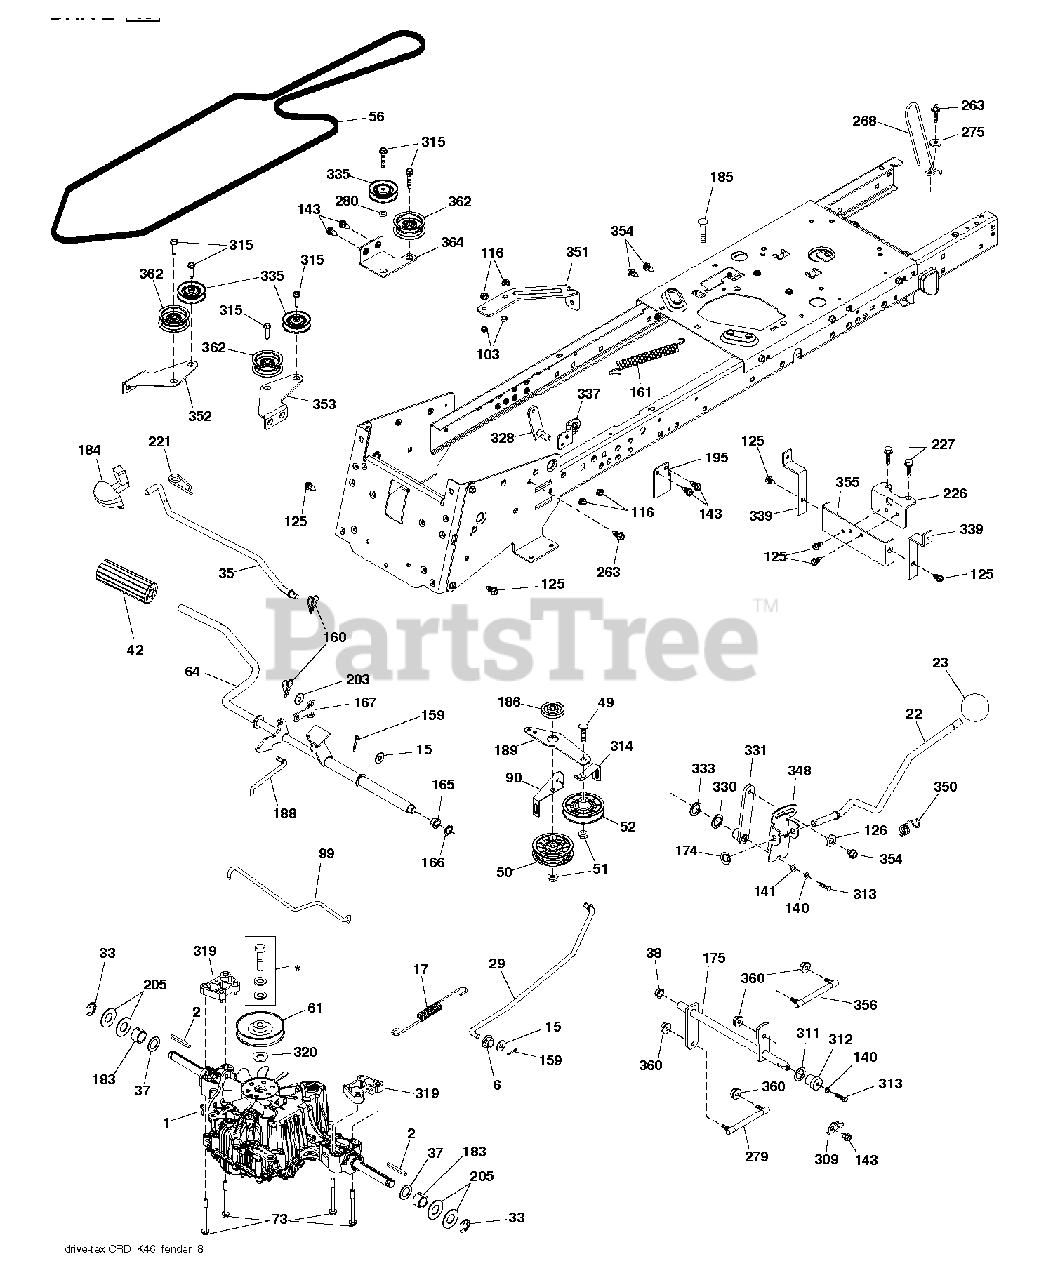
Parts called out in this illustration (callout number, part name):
2	SQUARE KEY
6	MANDREL ASS'Y
23	PISTOL KNOB
33	E-RING LT
35	ROD, BRAKE, PARK
37	WASHER.HARDENED
38	NYLINER SNAP 5/8" ID
42	PEDAL COVER T
49	BOLT
51	NUT LOCK FLG 3/8-16 UNC
52	IDLER.V-GROOVE.910.OFFSET
64	SHAFT.ASM.PEDAL.BRAKE.
73	BOLT.HEX.FLNG.5/16-18X3.75
103	JAM NUT TI
116	NUT LOCK HEX FLANGE 5/16-18
125	SCREW
126	WASHER.SRRTD.5/16
140	LOCKWASHER
141	WASHER LT
159	COTTER PIN
160	RETAINER CLIP
161	SPRING, RETURN LT
165	BUSHING.SHAFT.BRAKE.HAND
166	NUT.PUSH.625
167	LATCH.BRAKE.SPRING
174	NUT.PUSH.500.2006
183	SPACER AXLE
184	Parking Brake Handle
186	SPACER.RETAINER
188	LINK.CLUTCH.GROUND.DRIVE
203	WASHER
221	RETAINER.SPRING.CLIP.H
226	BRACKET.MOUNT.TORQUE.K46.TLT
227	SCREW
275	WASHER
309	PLATE FASTENING LT
311	WASHER NYL
315	BOLT.5/16-18X1.25
320	WASHER.SPACER.MANDREL
330	WASHER.NYL.7/8IDX.105"HYD CR
331	HUB.SHIFT
335	PULLEY.V-IDLER.
